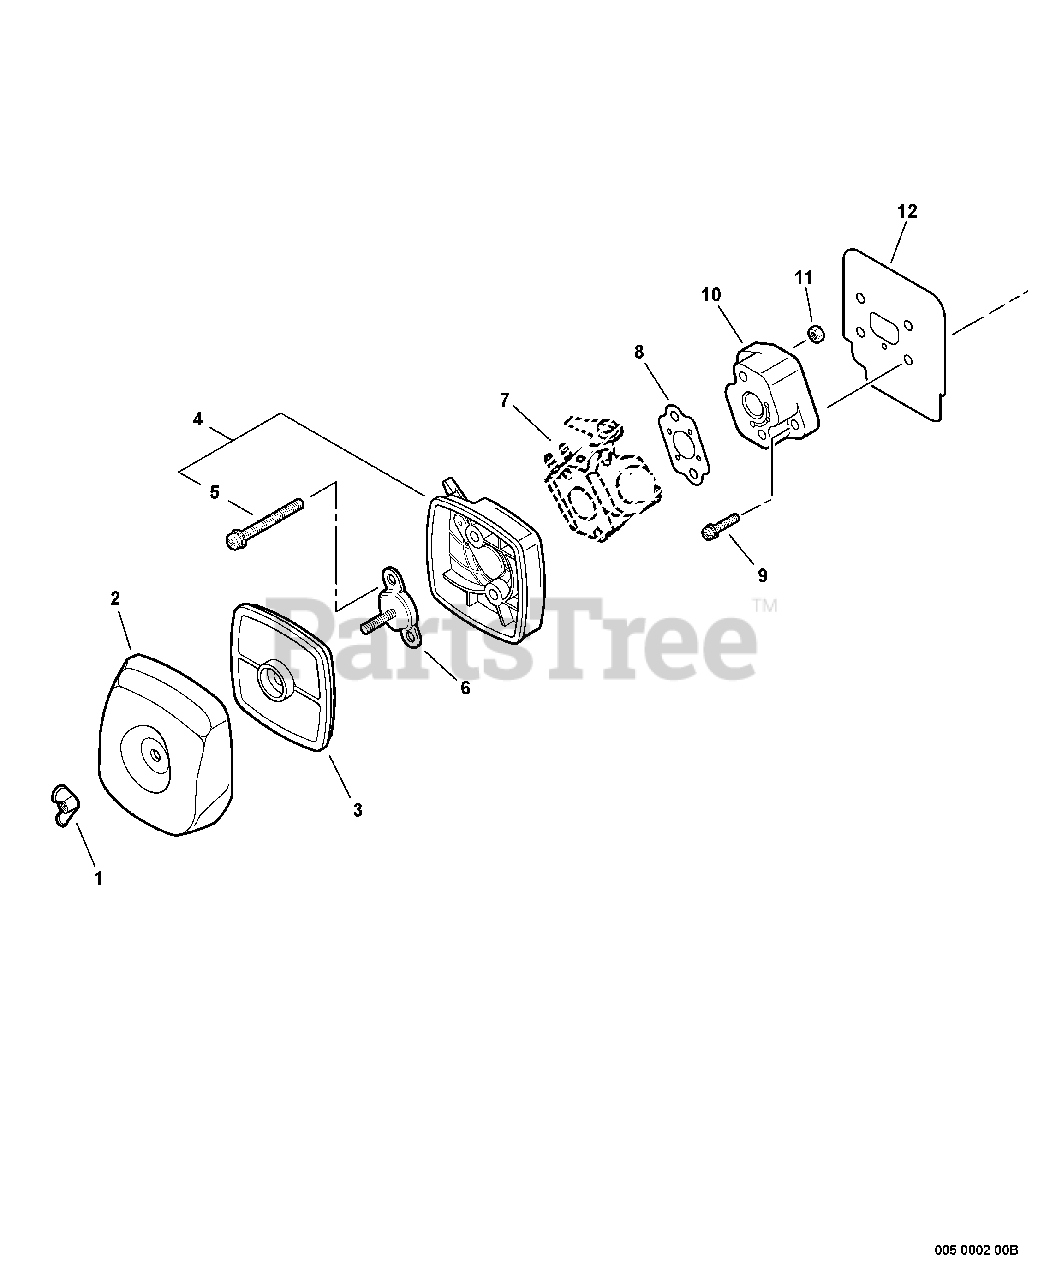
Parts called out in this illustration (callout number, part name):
1	WINGNUT - 6
2	COVER, AIR FILTER - GRAY
3	FILTER, AIR - SINGLE LAYER
4	AIR FILTER CASE KIT - GRAY
5	SCREW - 5X65
6	PLATE, PREVENT
7	CARBURETOR
8	GASKET, INTAKE
9	SCREW - 5X20
10	INSULATOR, INTAKE
12	SHIELD, INTAKE
